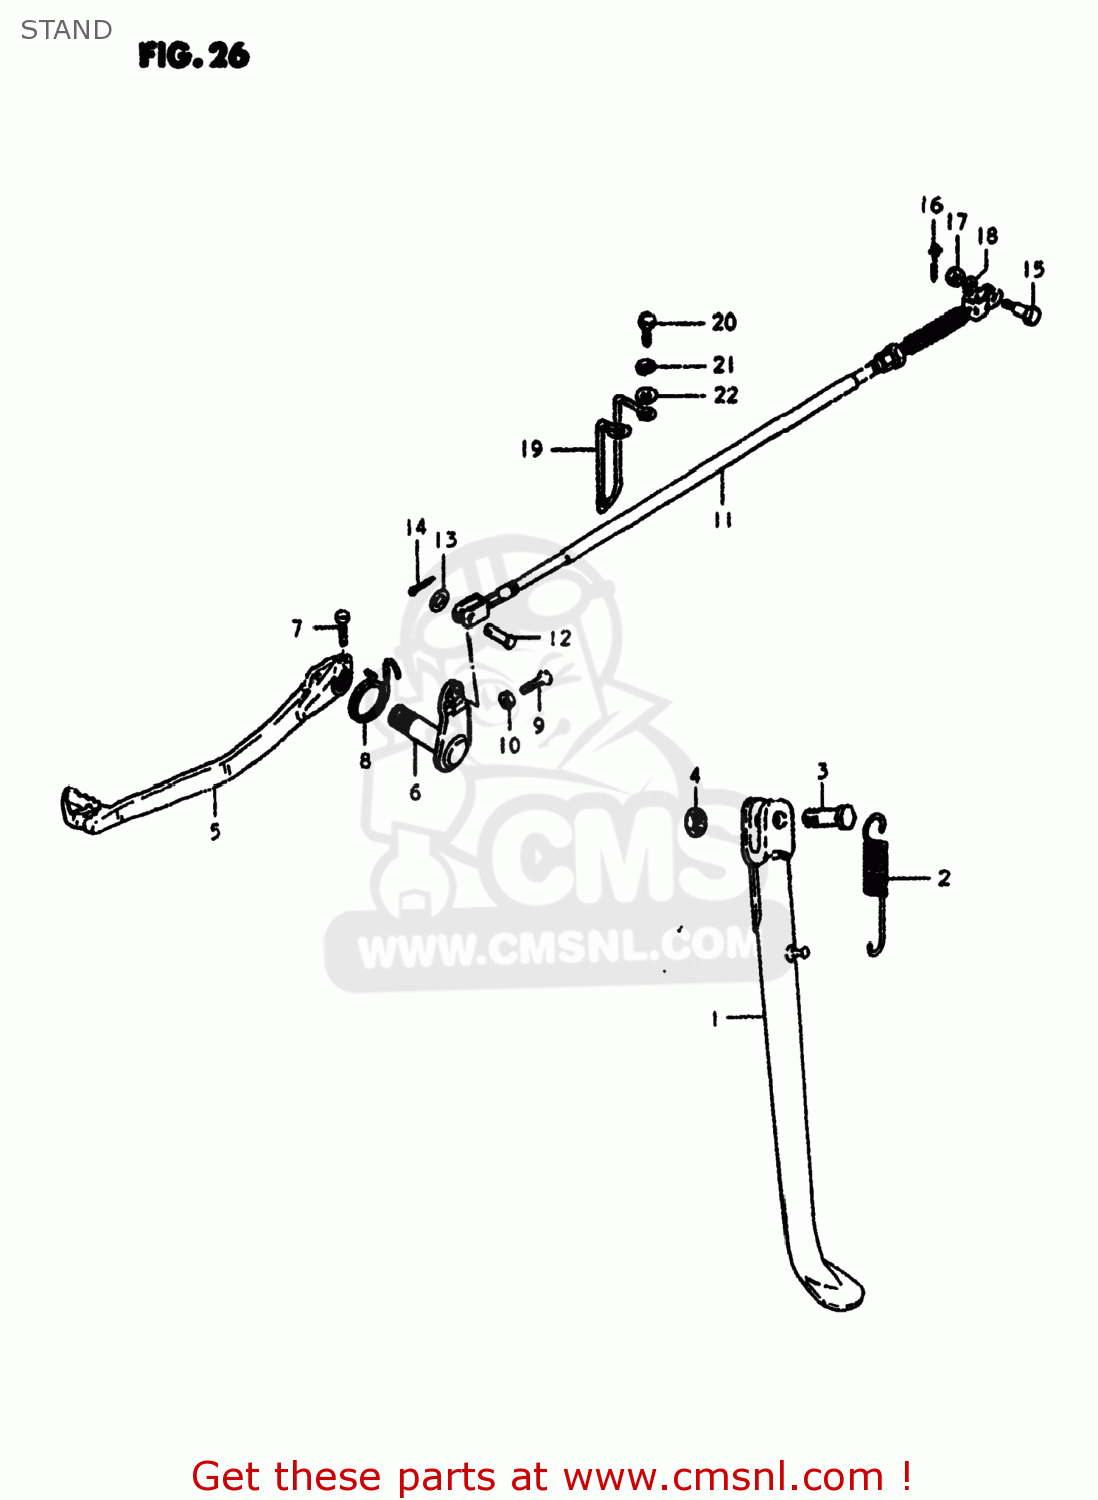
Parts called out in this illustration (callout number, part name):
1	STAND,SIDE
2	SPRING
3	BOLT(10X30)
4	NUT
5	PEDAL,BRAKE
6	ARM,BRAKE PEDAL
7	BOLT
8	SPRING
9	BOLT(6X23)
10	NUT
11	CABLE,RR BRAKE
12	PIN(L:17.5)
13	WASHER
14	PIN
15	BOLT
16	PIN
17	NUT
18	SHIM (8.5X16,5X0.8)
19	GUIDE,BRAKE CABLE
20	BOLT
21	LOCK WASHER
22	WASHER
